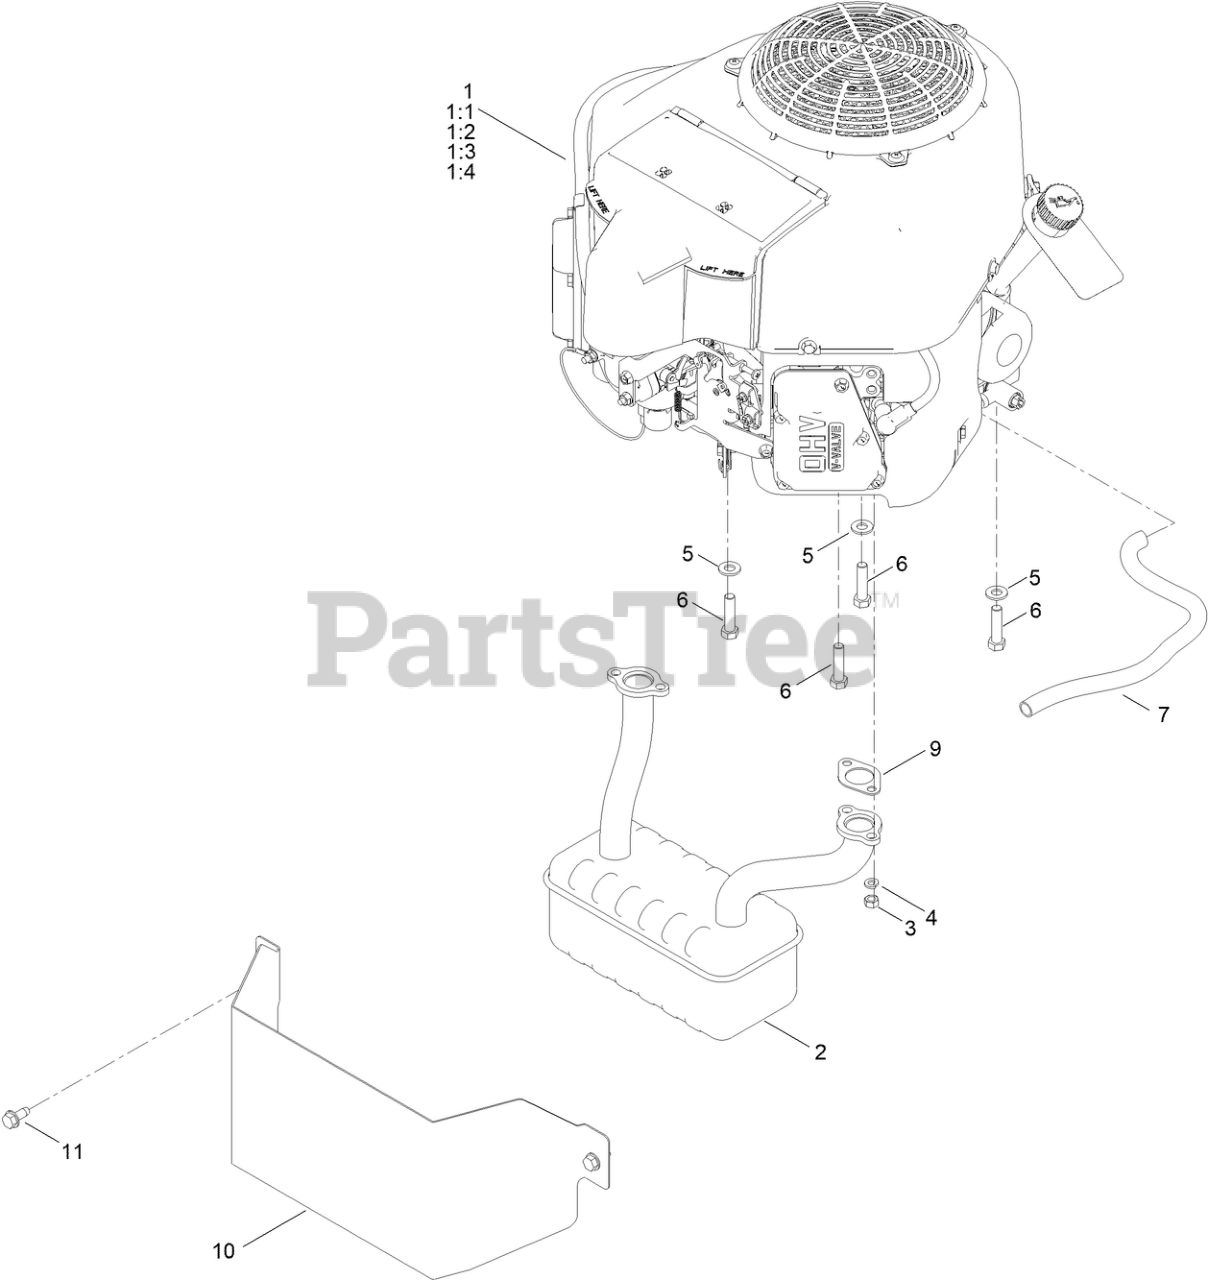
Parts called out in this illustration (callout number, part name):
1:1	FILTER-OIL
1:2	Filter-Fuel
1:3	PLUG-SPARK
1:4	FILTER-AIR, PAPER
2	MUFFLER
4	WASHER-LOCK
5	WASHER-FLAT
6	BOLT-HH
7	TUBE-DRAIN, OIL
9	GASKET-EXHAUST
10	HEAT SHIELD - MUFFLER
11	SCREW-HWHTF
